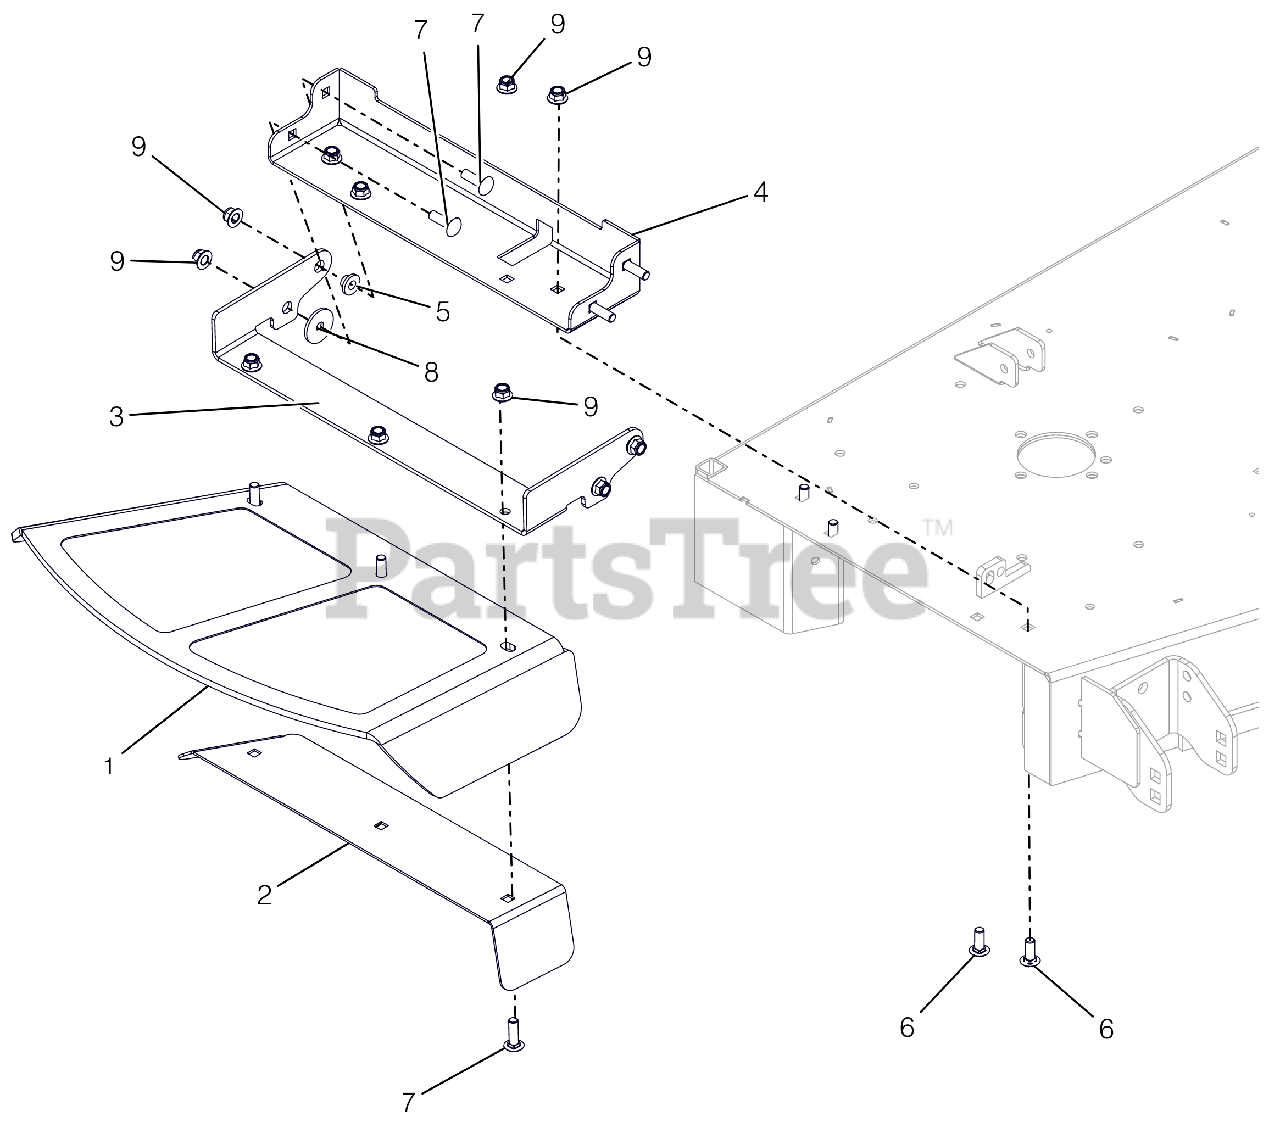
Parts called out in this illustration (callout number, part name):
1	CHUTE,48-60" FRMD RUBBER DISCH
2	PLT, DISCH. CHUTE CLMP-CE
3	BRKT, CE CHUTE MTG
4	WMT, DISCH. CHUTE-CE-W/SAFETY
5	BSHG-FLG .385X.500X.875X.406
6	@BLT-RDHDSHSQNK.38-16X1.0 G5YZ
7	@BLT-RHDSSQNK .38-16X1.25 G5YZ
8	WSHR-FL-STL .380X1.50X.125YWZC
9	@NUT-LK-NYL-FLG .38-16 YWZC
